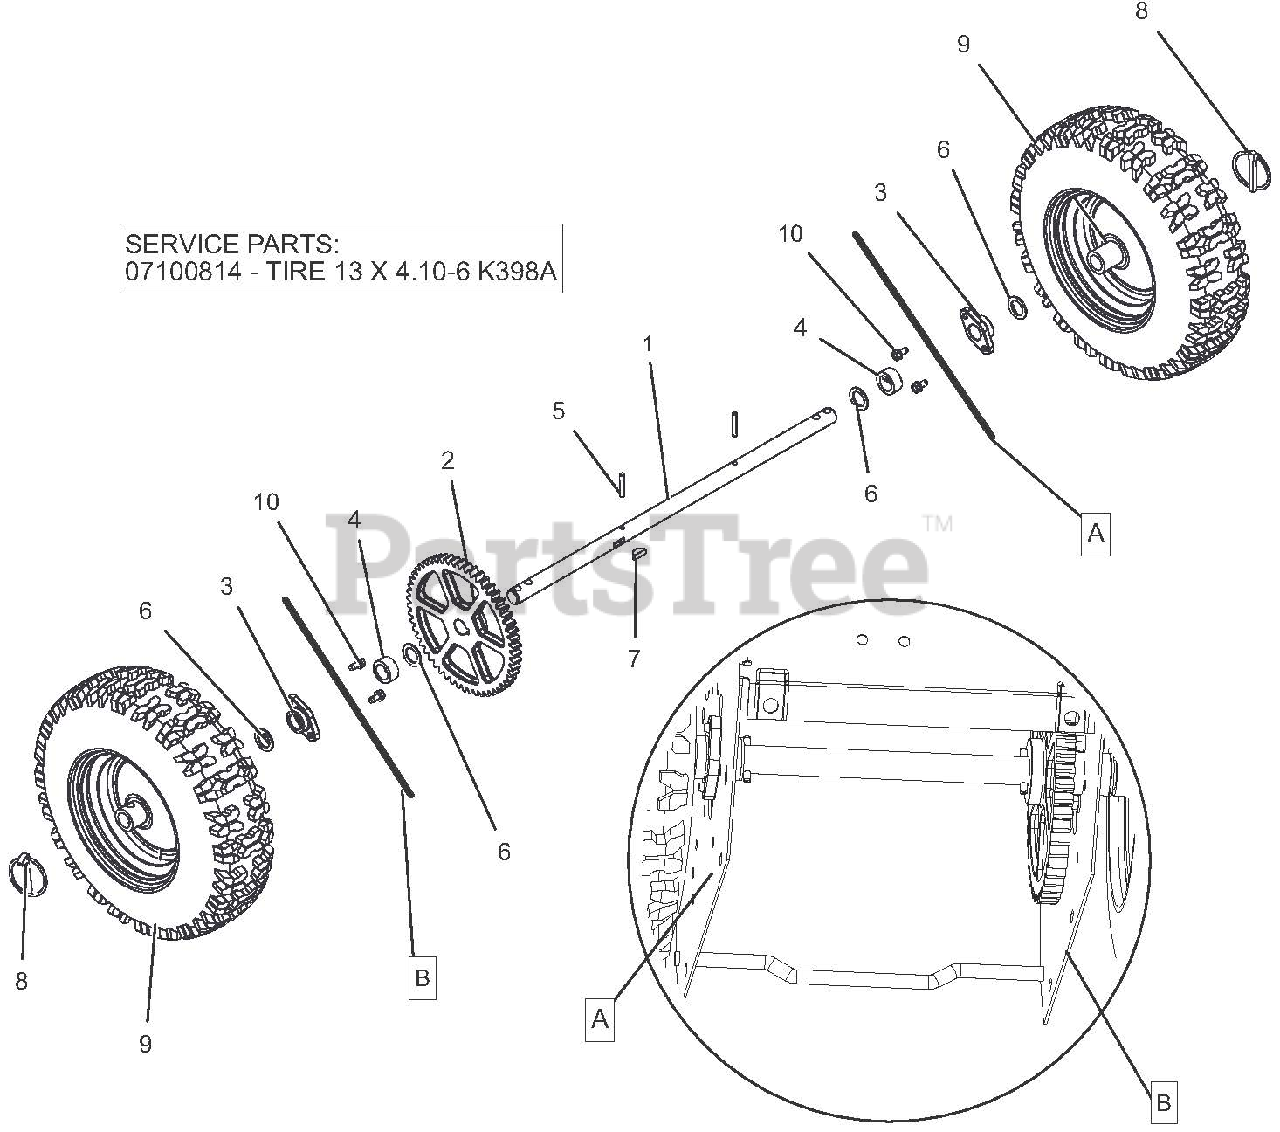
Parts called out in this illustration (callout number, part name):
1	SHAFT, AXLE
2	SPUR GEAR, 54T .75ID X 6.75PD
3	BSHG .75X1.125X.65
4	BSHG-SLV .766 X 1.125 X .500
5	PIN-ROLL .188X1.25
6	WSHR-FL-STL.754X1.125X.062YWZC
7	KEY-WDRF .25X.750X.313 SAE91
8	PIN-LOK .31X1.75
9	TIRE/WHEEL, 13X4.10-6 K398A
9	TIRE, 13" K398A
9	TUBE
10	SCR-TAP .25-20X.50 HWH TR YWZ
